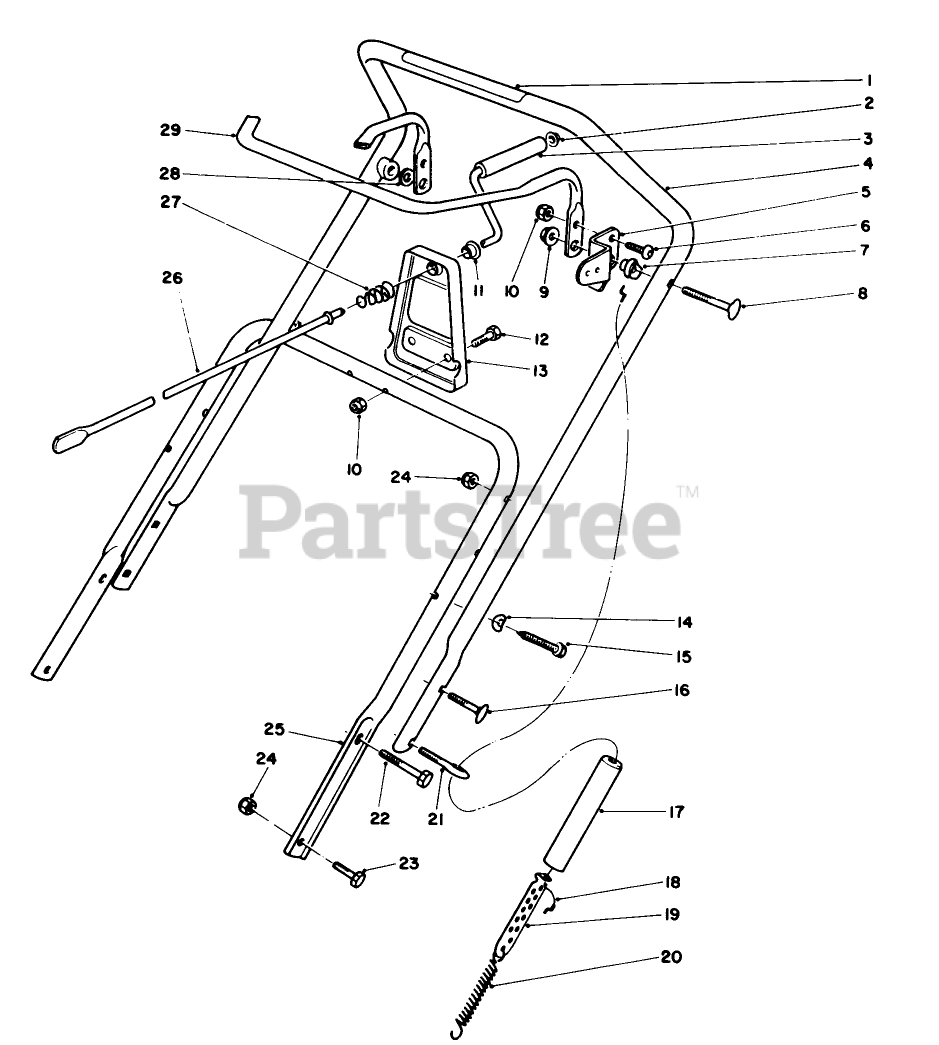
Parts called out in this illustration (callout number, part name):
1	DECAL - ROTOR DRIVE
2	RETAINER-PUSH ON
3	Grip-Rod
4	Upper Handle Assembly (Incl. Ref. #1)
5	Arm-Clutch Cable
6	SCREW-HSBH
7	SPACER-BAR, CONTROL
8	SCREW-HANDLE
9	SCREW-HH
10	NUT-LOCK, NI
11	Bushing
12	SCREW-HH
13	Support-Crank
14	WASHER
15	SCREW
16	SCREW
17	COVER-SPRING
18	CABLE-CLUTCH
19	ADJUSTER-CABLE
20	SPRING-EXTENSION
21	BOLT-EYE
22	SCREW-HH
23	SCREW-HH
24	NUT-LOCK, NI
25	LOWER HANDLE
26	ROD-CRANK, CHUTE
27	SPRING-COMPRESSION
28	WASHER
29	Bar-Control
